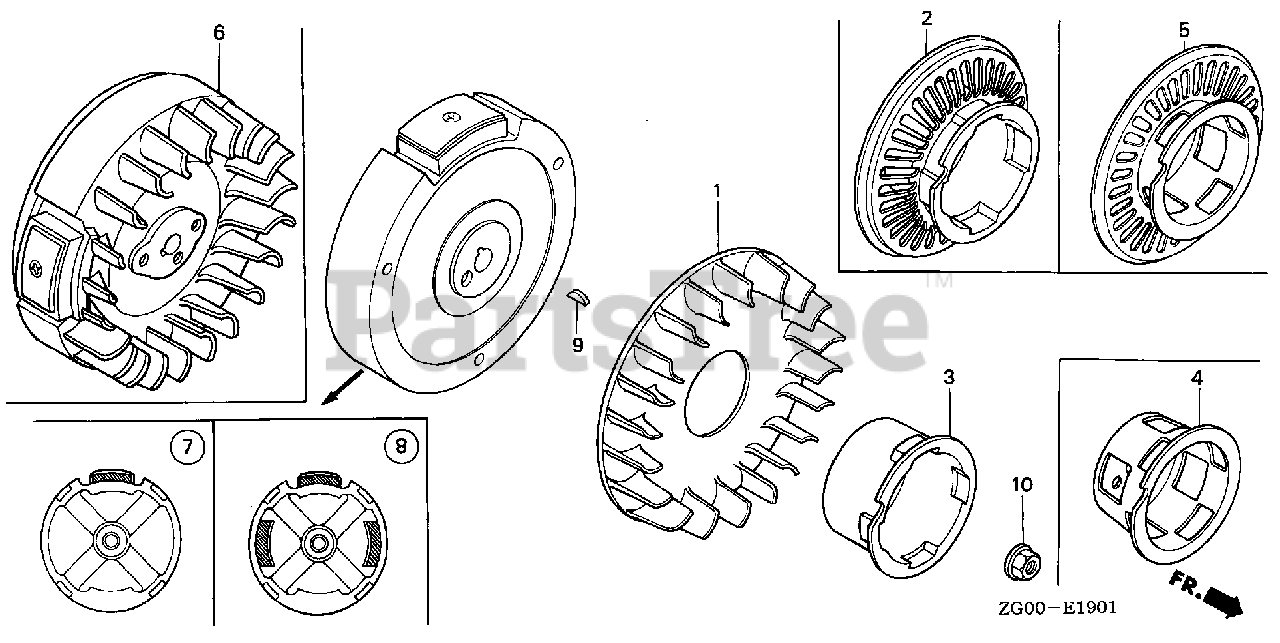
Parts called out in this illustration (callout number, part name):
1	FAN, COOLING
3	PULLEY, STARTER
9	KEY, WOODRUFF (3MM)
10	NUT, FLANGE (12MM)
